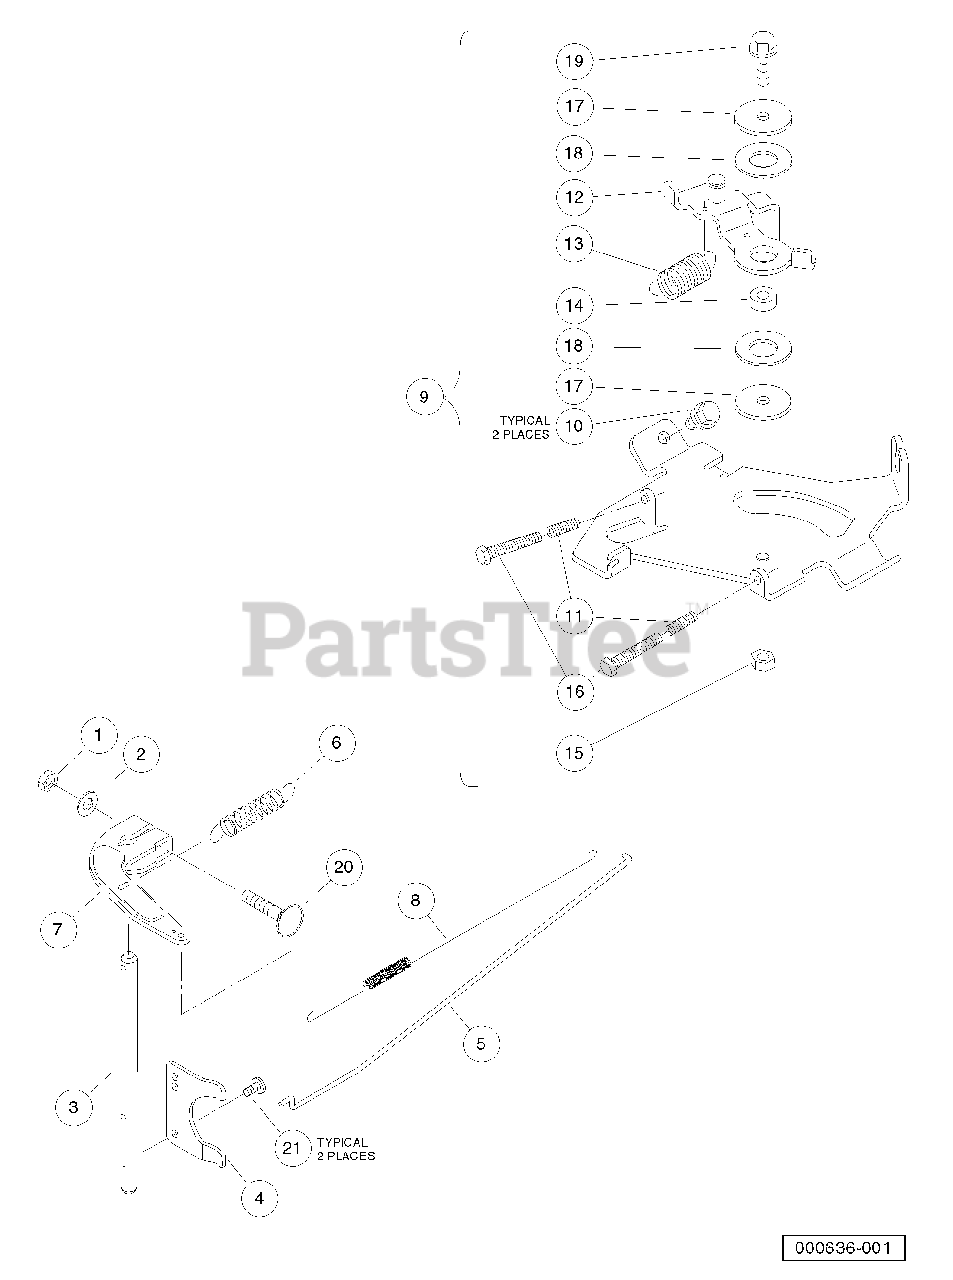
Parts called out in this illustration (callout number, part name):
2	Washer, M6 Flat
3	Shaft, Governor, Fh
4	Plate, Governor, Fh
5	Link, Arm, Governor, Fh
6	Spring, Governor, Fh
7	Arm, Governor, Shaft
8	Spring, Arm, Governor, Fh
9	Panel, Control, Complete, Fh
10	Bolt, Flg, M6 X 1.0 X 12
11	Spring, Fh
12	Lever, Governor, Control, Fh
13	Spring, Governor Return, Fh
14	Collar, Governor, Fh
15	Nut, Governor, Fh
16	Bolt, Speed Control, Fh
17	Washer, Governor, Lower, Fh
18	Washer, Governor, Middle, Fh
19	Bolt, Flanged, M6 X 20, Kaw
20	Bolt, M6 X 35, Kawasaki
21	Screw, Pan, Governor, Fh
